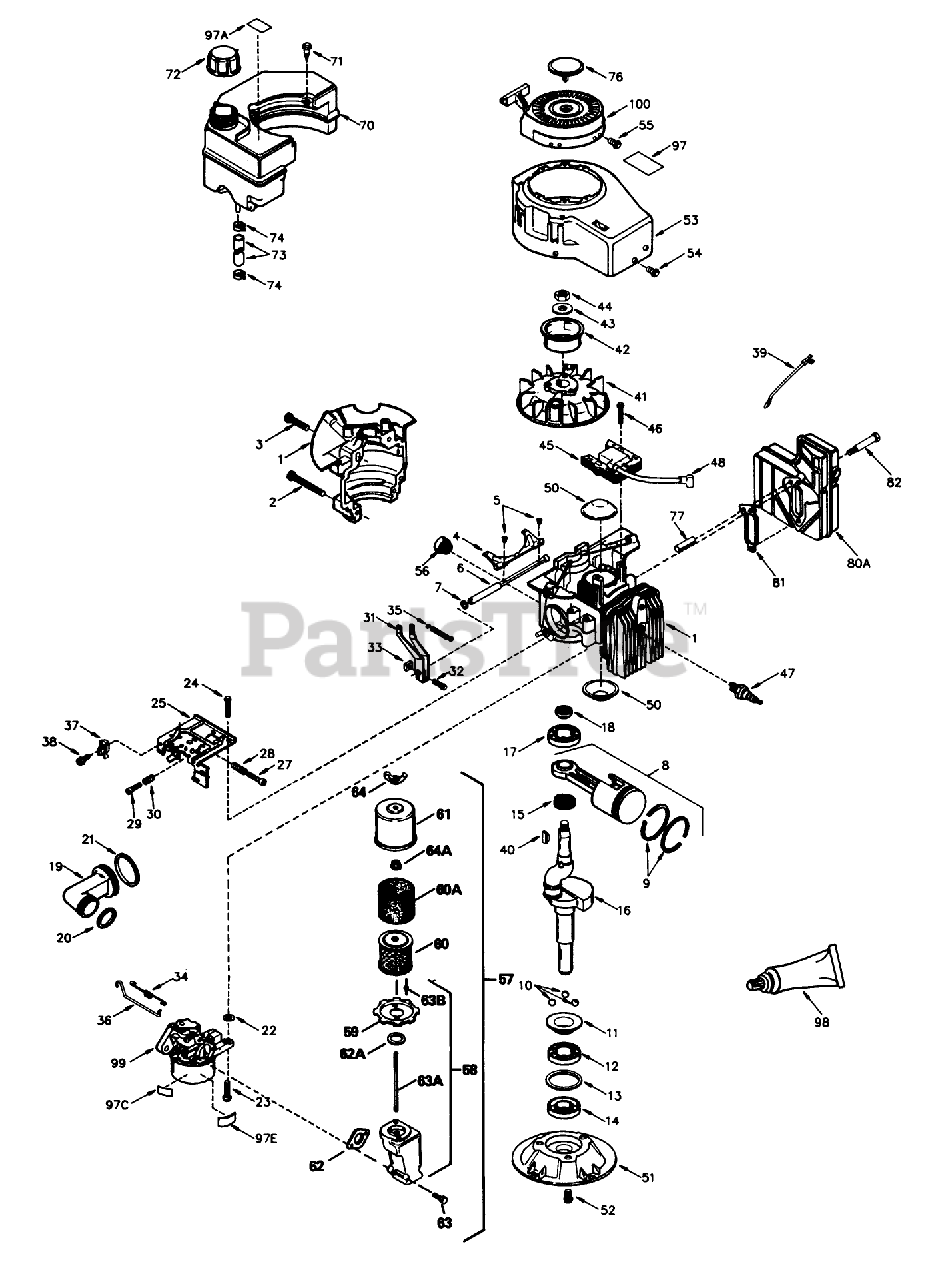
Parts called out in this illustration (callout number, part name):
2	Screw
3	Screw
4	Governor Lever
5	Screw-Shutter
6	Governor Shaft
7	Oil Seal
8	Piston Rod Assy. (Incl. Ref. #9 15)
9	Ring Set-Piston
11	Ring-Slide
12	Ball Bearing
13	Bearing Retainer
14	Oil Seal
15	Bearing-Strip
16	Crankshaft
17	Ball Bearing
18	Oil Seal
19	Intake Pipe Assy. (Incl. Ref. #20 21
20	O Ring
21	O Ring
22	Washer-Bowl Nut
23	Screw-Hex. Washer Hd.
24	Screw (10-24 x 3/8)
25	Control Bracket Assy. (Incl. Ref. #27 thru 30)
27	Screw-Phillips Hd.
28	Spring
29	Screw
30	Spring-Compression
31	Lever-Governor
32	Screw
33	Nut-Lock
34	Spring-Throttle Link
35	Spring-Governor
36	Link-Governor
37	Conduit
38	Screw-Hex. Hd.
39	Wire-Ground
40	Key-Flywheel
41	Flywheel
42	Cup-Starter
43	Washer-Belleville
44	Nut-Flywheel
45	Solid State
46	Screw
47	Spark Plug-Resistor (R C J 8Y)
48	Cover-Spark Plug
50	Cover-Port
51	Adapter
52	Screw-Hex. Washer Hd.
53	Housing-Blower
54	Screw
55	Screw, Hex Hd.
56	Filter-Fuel
57	Dual Upright Canister Air Cleaner Kit (Incl. Ref. #58, 60, 60A, 61, 62, 63, 64 97B)
58	Elbow Assy., Air Cleaner (Incl. Ref. #59, 62A, 63A 63B)
59	Bracket-Air Cleaner
60	Filter, Air Cleaner (incl. Ref. #64A)
60A	Filter-Pre-Air
61	Body, Air Cleaner
62	Gasket-Air Cleaner
62A	Gasket, Air Cleaner
63	Screw, Fil hd.
63B	Rivet-Pop
64	Nut-Wing
64A	Nut Lockwasher
70	Fuel Tank Assy.
71	Screw-Hex. Hd.
72	Cap-Fuel
73	Line-Fuel (8.62)
74	Clamp-Line, Fuel
76	Plug Starter
80A	Muffler
81	Gasket-Muffler
82	Screw-Hex. Hd.
97	Decal-Name
97A	Decal-Fuel Mixture
97C	Decal-Primer
97E	Decal-Instruction
98	Gasket Eliminator
99	Contact Assy., Breaker
100	Starter-Rewind
